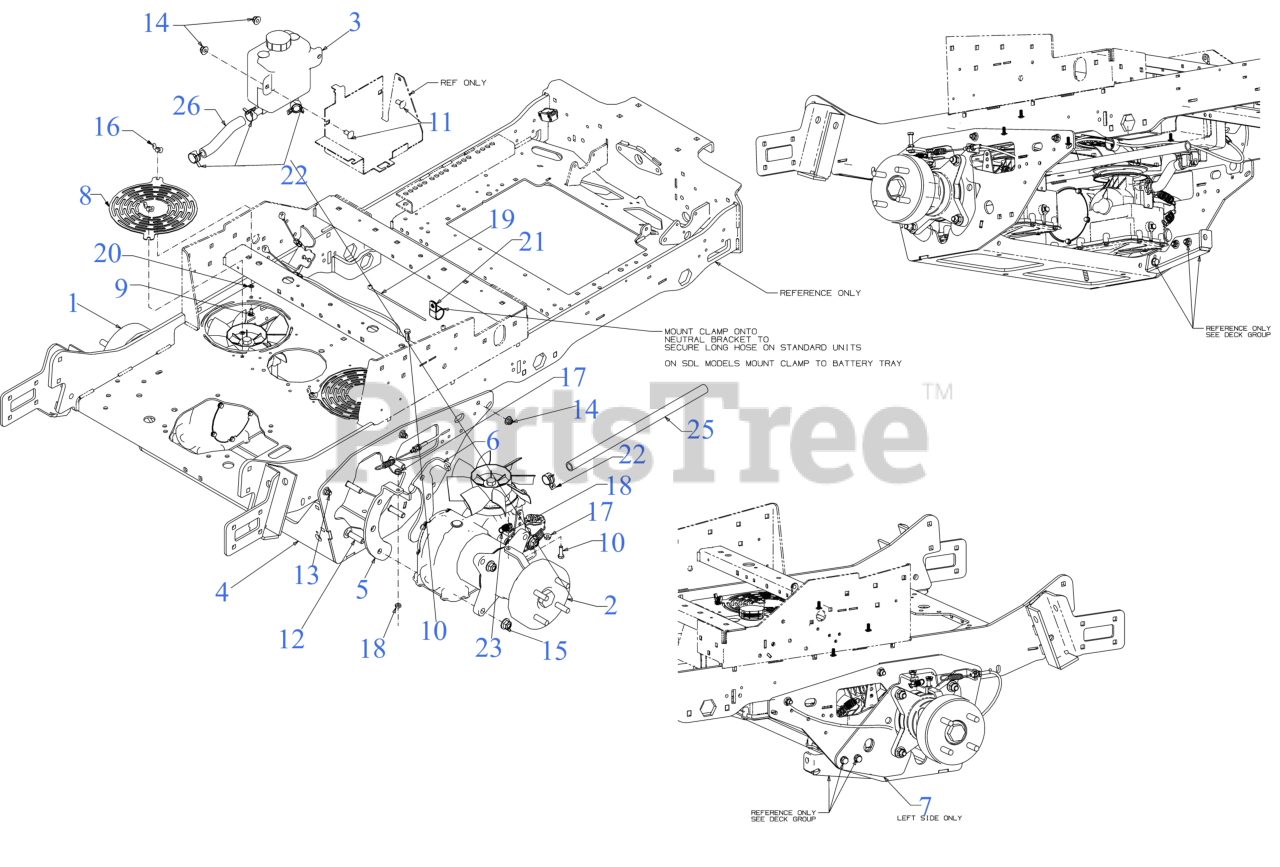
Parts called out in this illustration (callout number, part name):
1	TRANSMISSION (LH)
2	TRANSMISSION (RH)
3	HYDRO TANK ASSEMBLY
4	TRANSMISSION MOUNTING BRACKET
7	BRAKE SPRING MOUNTING BRACKET (LH)
8	TRANSMISSION COVER PLATE
9	CARRIAGE BOLT 1/4-20 x .62
10	SCREW 5/16-18 x 1.0 GR5
11	CARRIAGE BOLT 3/8-16 x .750 GR5
12	CARRIAGE BOLT 1/2-13 GR5
13	CARRIAGE BOLT 3/8-16 X1.25 GR5
16	WING NUT 1/4-20
17	HEX FLANGE NUT
19	7" CABLE TIE
20	RETAINER-BOLT .25ID x .50OD
21	HOSE CLAMP 1.0"
22	HOSE CLAMP
23	EXTENSION SPRING .500 OD x 1.71
24	Cylinder Head Assy(CarburetorEngine)
25	OIL HOSE 5/8 ID x 18.00 LG
